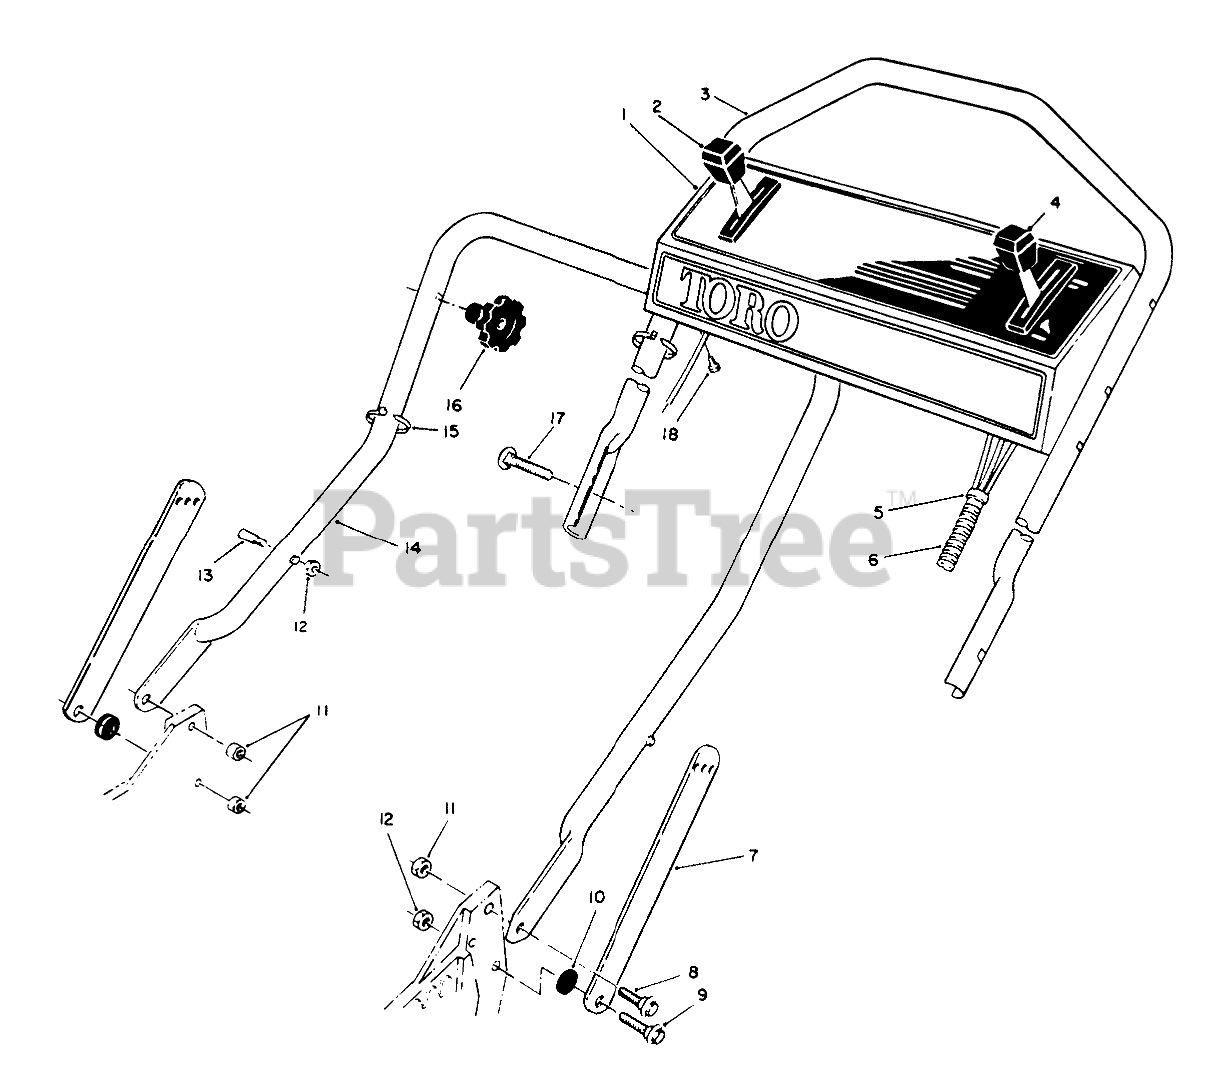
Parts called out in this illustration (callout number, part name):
1	SILK SCRN CONTROL PANEL
2	GROUND SPEED CONTROL
3	Handle-Upper
4	THROTTLE CONTROL
5	FITTING-RING
6	CONTROL CABLE COVER
7	Handle Latch
8	SCREW-SHOULDER
9	SCREW-SHOULDER
10	SPACER
11	NUT-LOCK, NI
12	NUT-LOCK, NI
13	HANDLE PIN
14	LOWER HANDLE ASM
15	TIE-CABLE
17	5/16-18 X 2 HNDLE SCREW
18	SCREW-HWHTF
